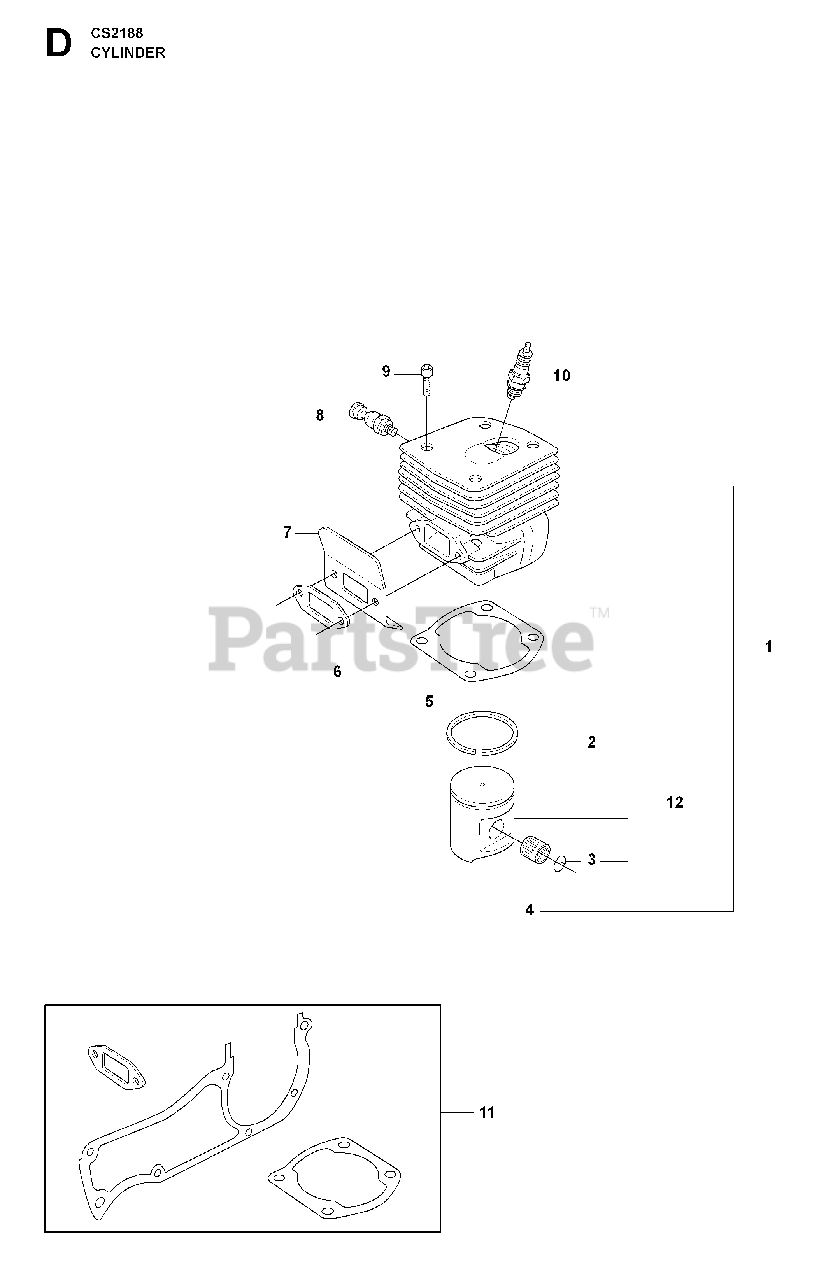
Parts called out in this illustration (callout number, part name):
1	CYLINDER ASSY
2	PISTON RING
3	CLIP
4	SUPPORT BUSHING
5	GASKET
6	GASKET
7	DEFLECTOR
8	DECOMPRESSION VALVE
9	SCREW MC6S 5X25
10	SPARK PLUG RCJ7Y
11	GASKET SET
12	PISTON ASSY
12	PISTON CPL 54 MM
